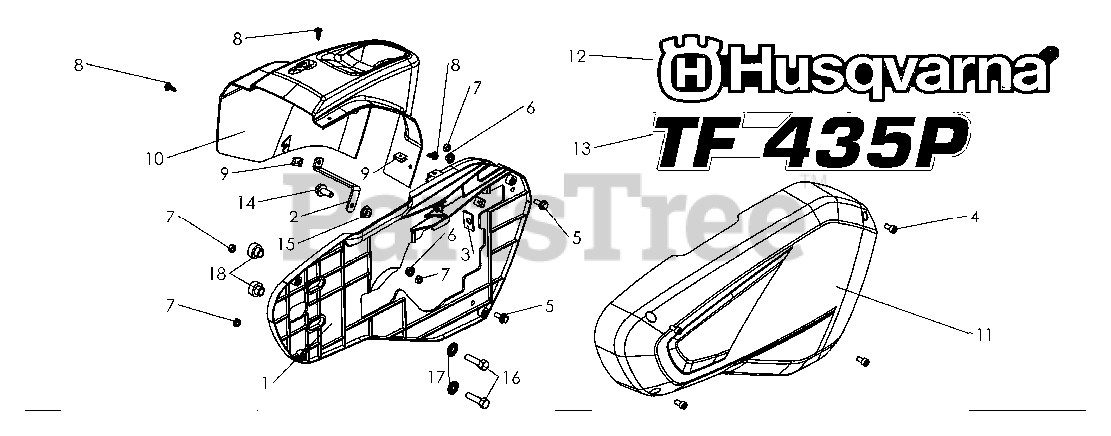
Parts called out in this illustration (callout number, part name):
5	SCREW
6	NUT
7	Blocking nut M 6 Z
8	SCREW
9	CLIP
14	NUT
15	NUT
